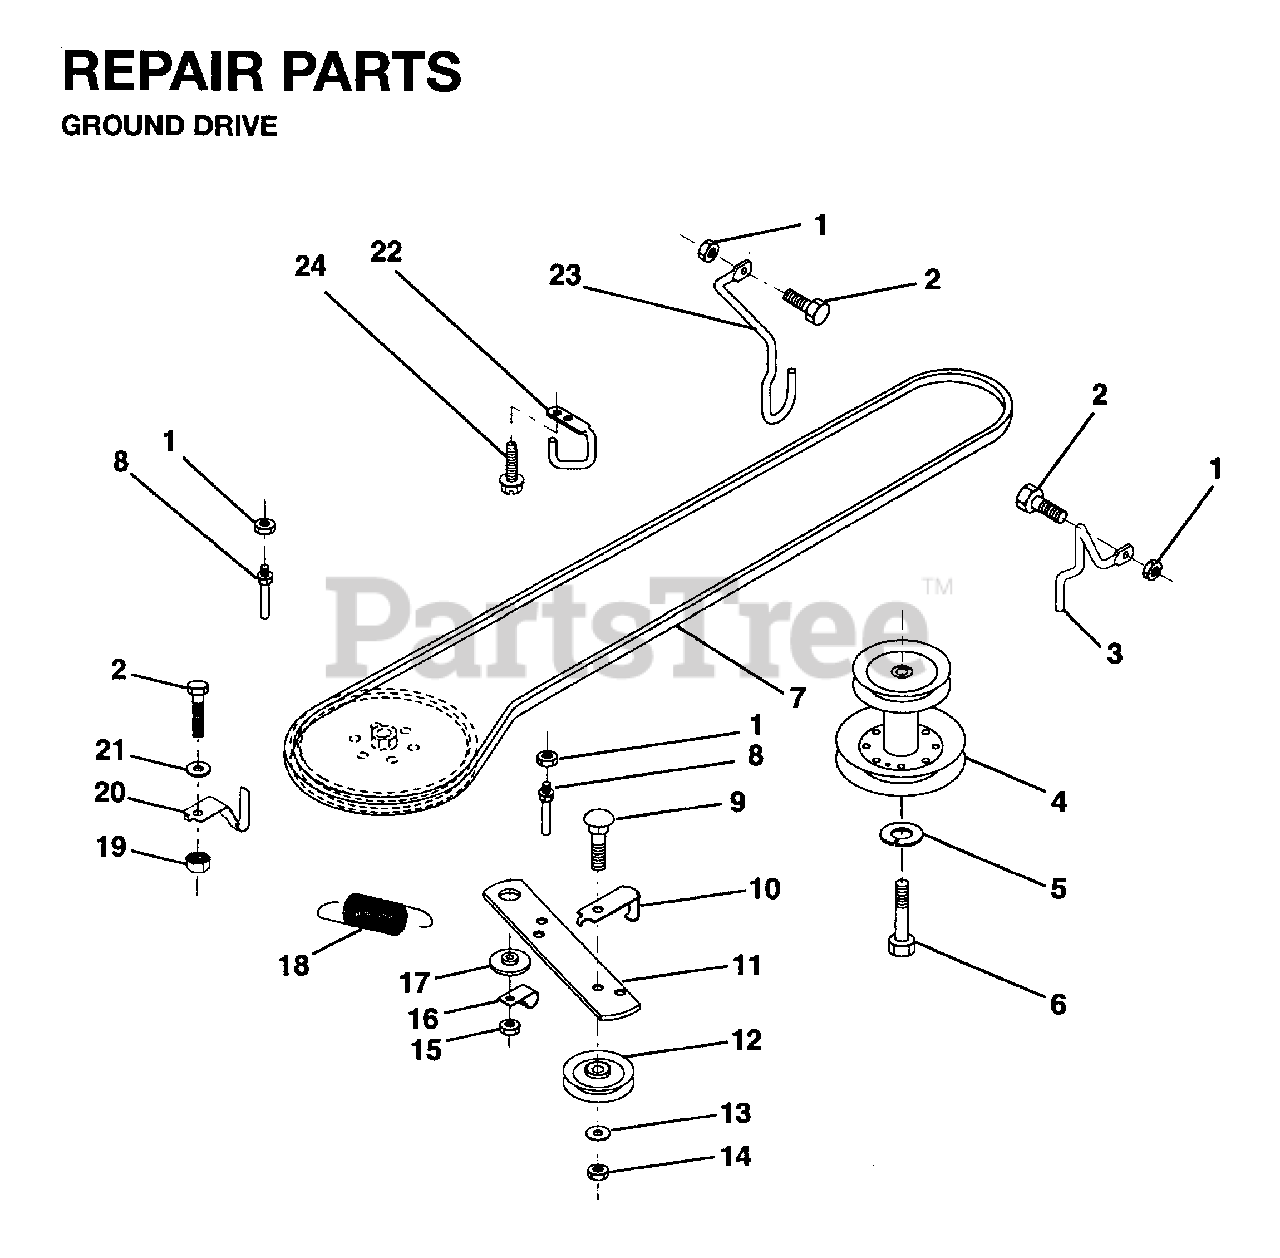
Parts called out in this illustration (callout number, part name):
1	LOCKNUT
2	BOLT
3	KEEPER/MOWER DRIVE RH
4	ENGINE PULLEY
5	LOCKWASHER
7	BELT
8	KEEPER,DRIVE BELT
10	KEEPER.BELT.GROUND.DRIVE.IDLER
11	ARM/GROUND DRIVE CLUTCH
12	PULLEY.IDLER.FLAT
13	WASHER
14	LOCKNUT
15	LOCKNUT
16	CLIP,INSULATOR
17	SPACER RETAINER
18	SPRING.EXTENSION
19	LOCKNUT
20	KEEPER-T/A GROUND DRIVE BELT
21	WASHER - 15X7.3X1.6
22	KEEPER,FRA DR BEL
23	KEEPER-MOWER DRIVE LH
24	BOLT
